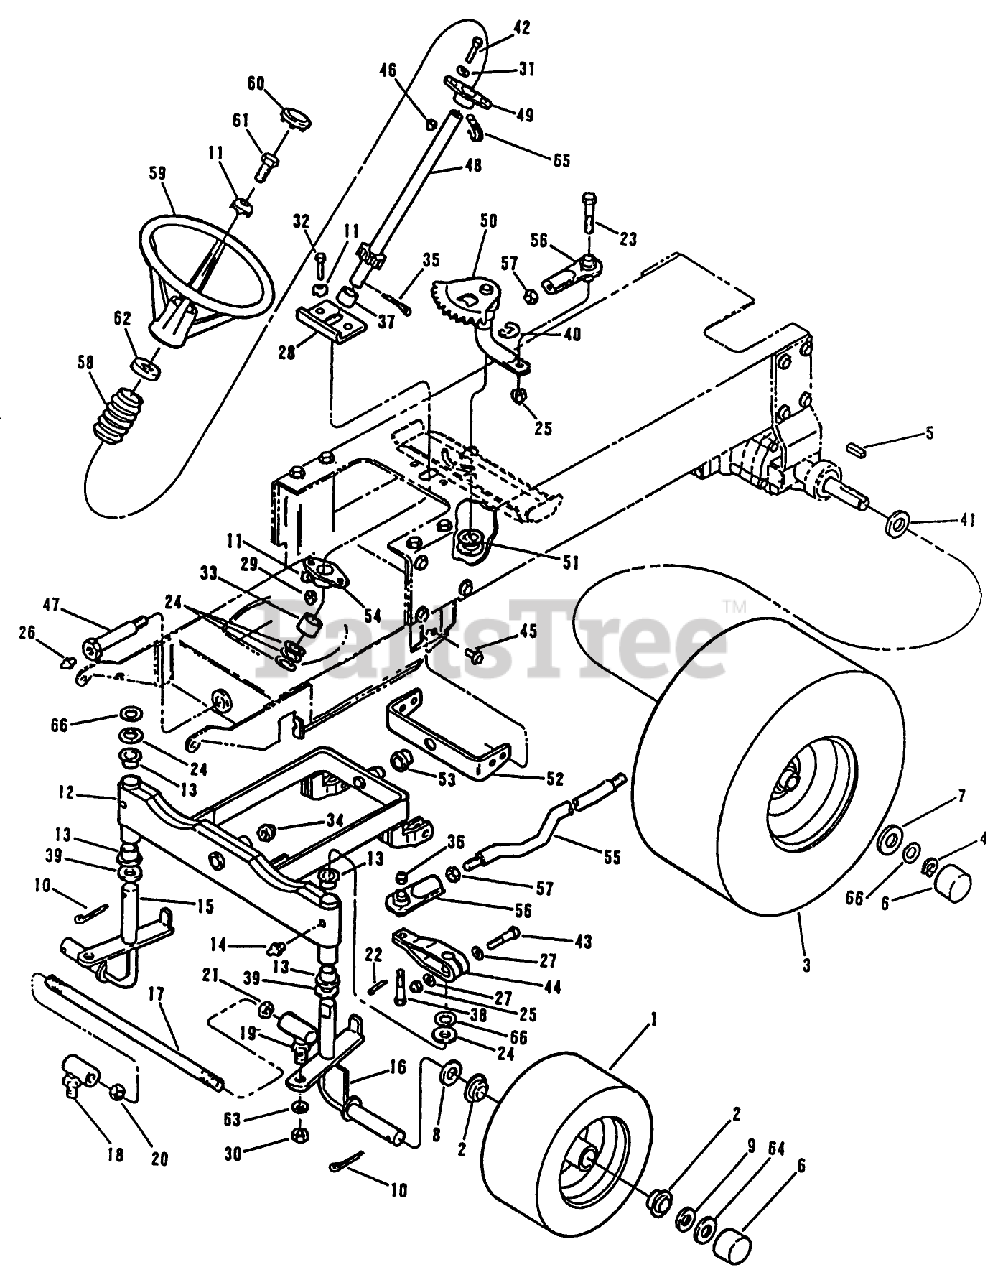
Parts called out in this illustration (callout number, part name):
5	KEY-SQUARE 1/4X1/4
9	WASHER
12	AXLE AY-FRONT
13	BEARING - BRONZE
16	SPINDLE ASM - LH
18	BALL JOINT, RH
19	BALL JOINT-LH
21	NUT HEX JAMB LH
24	SPACER
25	NUT-LOCKING
27	WASHER
29	NUT
30	HEX NUT
32	SCREW
34	NUT-HEX
37	SPACER
39	WASHER - THRUST
41	CLAMP-HOSE
42	SCREW-HH
46	NUT-LOCK, CONE
49	BEARING AY.
56	BALL JOINT
57	NUT-HEX
61	SCREW - HEX
65	CLAMP - J EX
66	WASHER - SPECIAL
